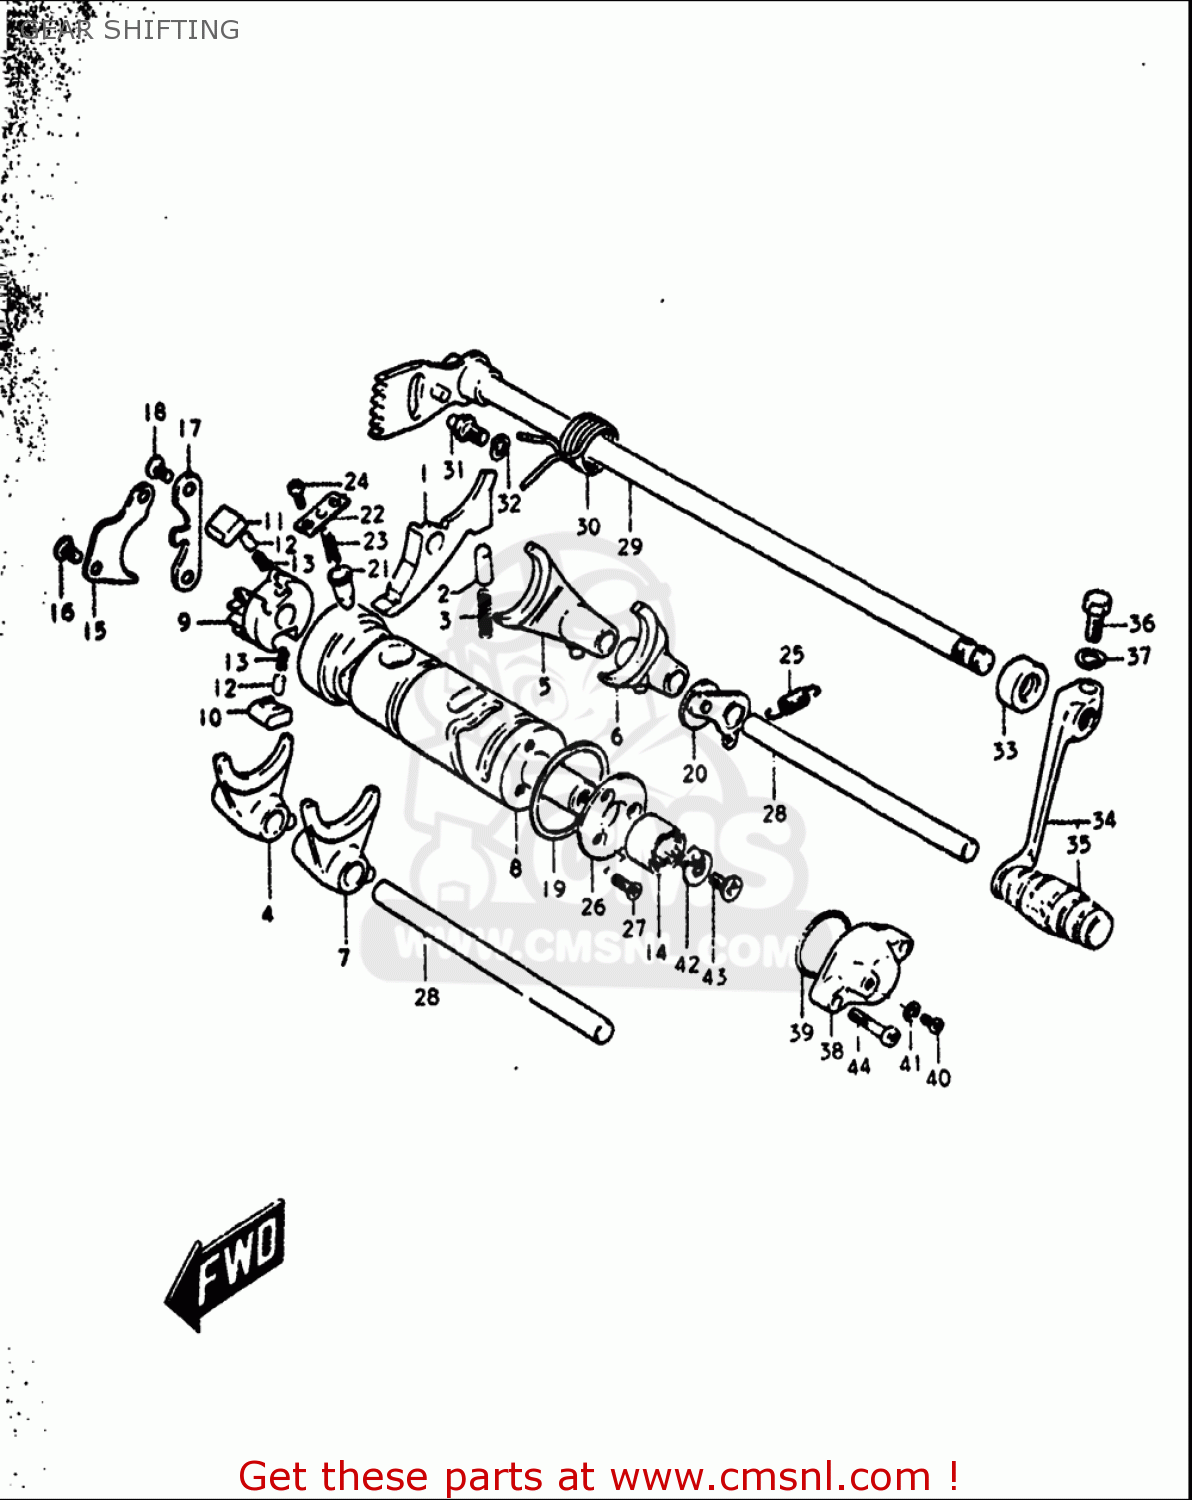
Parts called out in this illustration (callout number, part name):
10	GEAR,GEAR SHIFT CAM DRIVEN
11	PAWL,GEAR SHIFT NO.1
12	PAWL,GEAR SHIFT NO.2
13	PIN(5X8)
14	SPRING
15	ROLLER BEARING (16X22X1
16	LIFTER,GEAR SHIFT PAWL
17	SCREW
18	GUIDE,GEAR SHIFT CAM
19	SCREW
20	WASHER(40X45X1)
24	SPRING
25	SCREW
27	SCREW
30	SPRING
31	STOPPER,GEAR SHIFT ARM
32	WASHER,LOCK
33	SEAL,OIL (12X22X9)
34	LEVER ASSY,GEAR SHIFT
35	RUBBER,GEAR SHIFT PEDAL
36	BOLT
37	WASHER,LOCK
38	BODY,GEAR SHIFT SWITCH
39	O RING(D:1.9,ID:27.7)
40	SCREW
41	WASHER
42	CONTACT,GEAR SHIFT SWITCH
43	SCREW
44	SCREW
